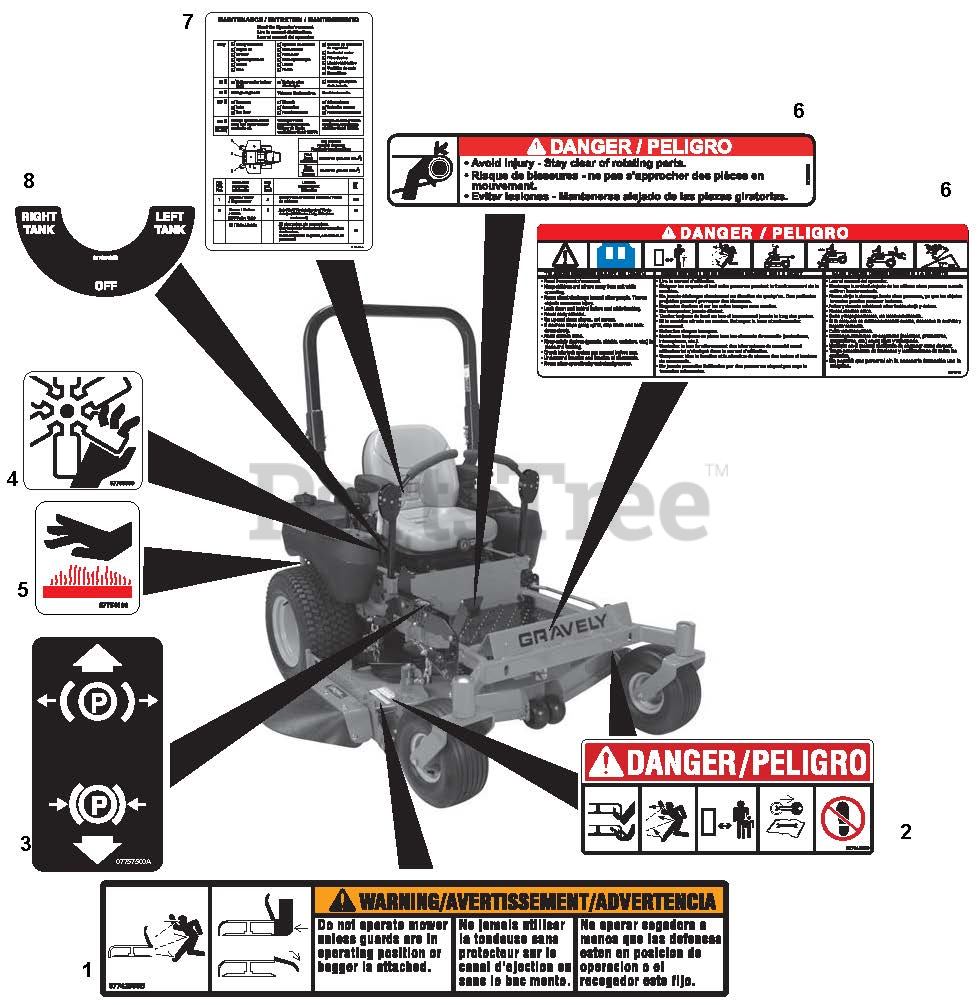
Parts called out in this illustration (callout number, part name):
1	Decal, Warning
2	Decal, Mower Pan Danger
3	Decal, Parking Brake Lever
4	Decal, Danger Fan
5	Decal, Hot Surface
6	Decal, Common Danger/Fuel
7	Decal, Maintenance Instructions
8	Decal, Fuel Control Valve
